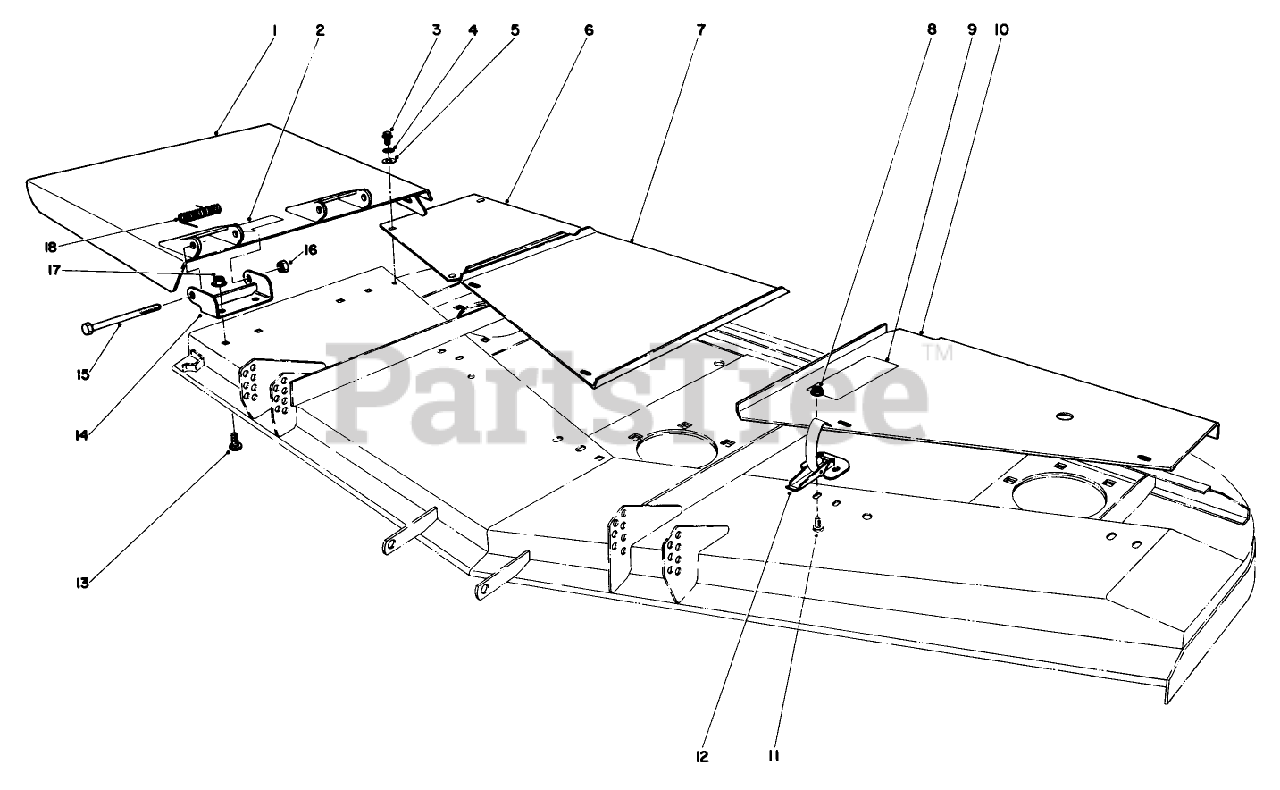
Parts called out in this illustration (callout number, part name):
3	SCREW THD 1/4 20 5/8
4	SCREW-HH
5	WASHER-FLAT
7	CTR DECK COVER *R
8	NUT-LOCK, FLANGE
11	SCREW-HWH
12	CLAMP-SLOTTED
13	SCREW-CARR
15	SCREW-HH
16	NUT-HEX
17	NUT-HHF, WHIZ
18	SPRING
